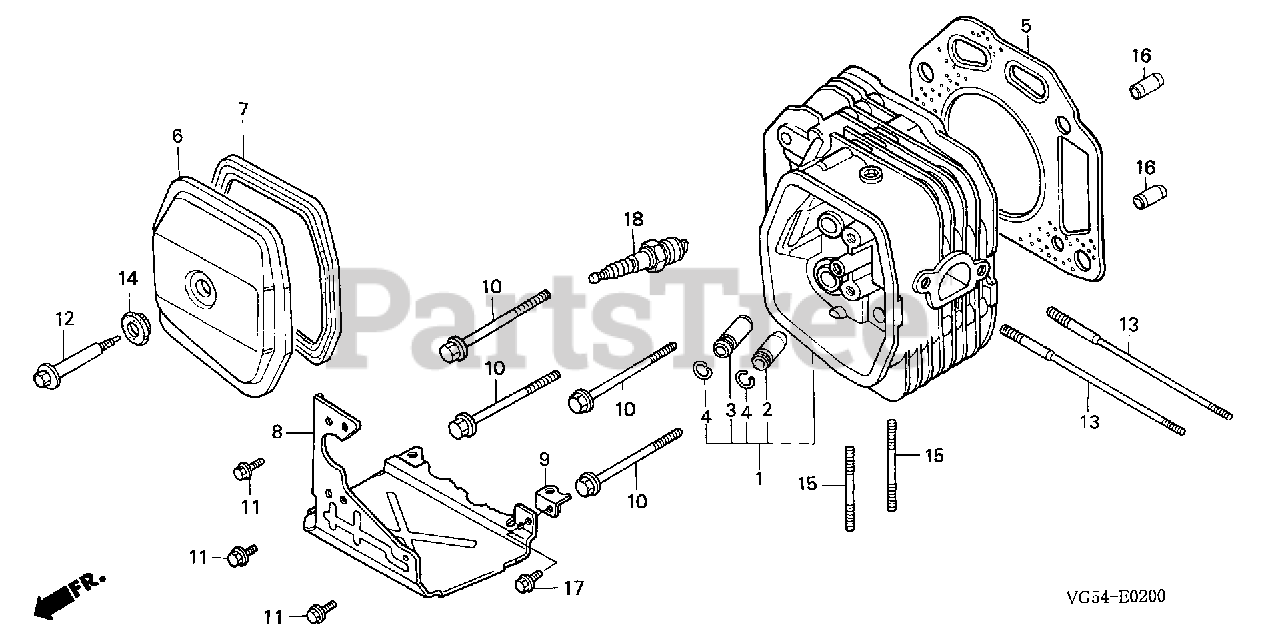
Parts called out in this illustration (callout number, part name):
1	CYLINDER HEAD
2	GUIDE, VALVE (OS)
3	GUIDE, EX. VALVE (OS)
4	CLIP, VALVE GUIDE
5	GASKET, CYLINDER HEAD
6	COVER, HEAD
7	GASKET, CYLINDER HEAD COVER
8	COVER (LOWER)
9	STAY, COVER (LOWER)
10	BOLT, FLANGE (10X85)
11	BOLT, FLANGE (6X12) (CT200)
12	BOLT, HEAD COVER
13	BOLT, STUD (8X131.5)
14	WASHER, HEAD COVER
15	BOLT, STUD (8X32)
16	PIN A, DOWEL (12X20)
17	BOLT, FLANGE (6X12)
18	SPARK PLUG (BPR5ES) (NGK)
